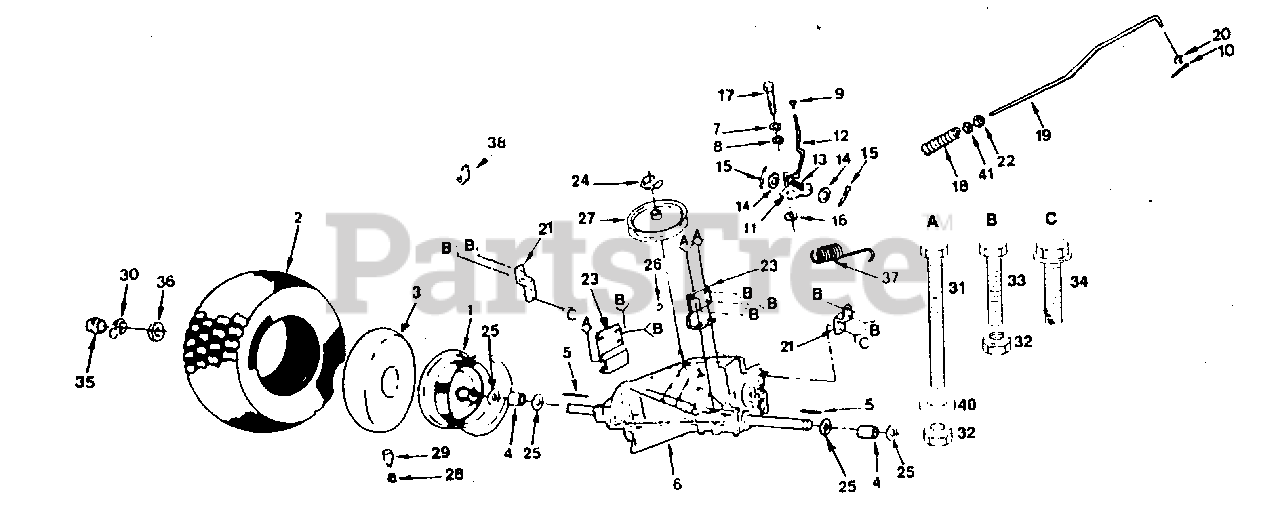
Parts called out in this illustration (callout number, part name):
1	Rim Assembly, Rear
2	Tire
3	Tube, Tire
4	Spacer, Split
6	Transaxle, Foote, Model No. 4360-7, 6-Speed
7	Washer, Lock 1/4
8	Washer 9/32 x 3/4 x 10 Ga.
9	Knob, Control
10	Pin, Cotter 1/8 x 3/4
11	Plate, Rod, Shift
13	Spring, Torsion
14	Washer 15/32 x 3/4 x 16 Ga.
15	Pin, Cotter 1/8 x 1
16	Washer, Shift Plate
17	Bolt, Hex 14-28 x 3/4 Gr. 8
18	Spring, Rod, Brake
19	Rod, Brake
20	Washer 13/32 x 13/16 x 16 Ga.
21	Strap, Torque
22	Nut, Hex, Jam 3/8-16
23	Bracket, Transaxle
24	Ring, Retainer
25	Washer 25/32 x 1-1/4 x 16 Ga.
26	Key, Woodruff # 9 3/16 x 3/4
27	Pulley, Input, Transaxle
31	Bolt, Hex 3/8-16 x 2-3/4
32	Nut 3/8-16
33	Bolt, Hex 3/8-16 x 3/4
34	Screw, Hex, Washer Hd., Thd. Form, Type TT 5/16-18 UNC x 3/4
36	Washer 25/32 x 1-5/8 x 16 Ga.
37	Spring, Brake Return
38	Clip, Fuel Line
40	Washer 11/32 x 3/4 x 14 Ga.
41	Locknut 3/8-16
